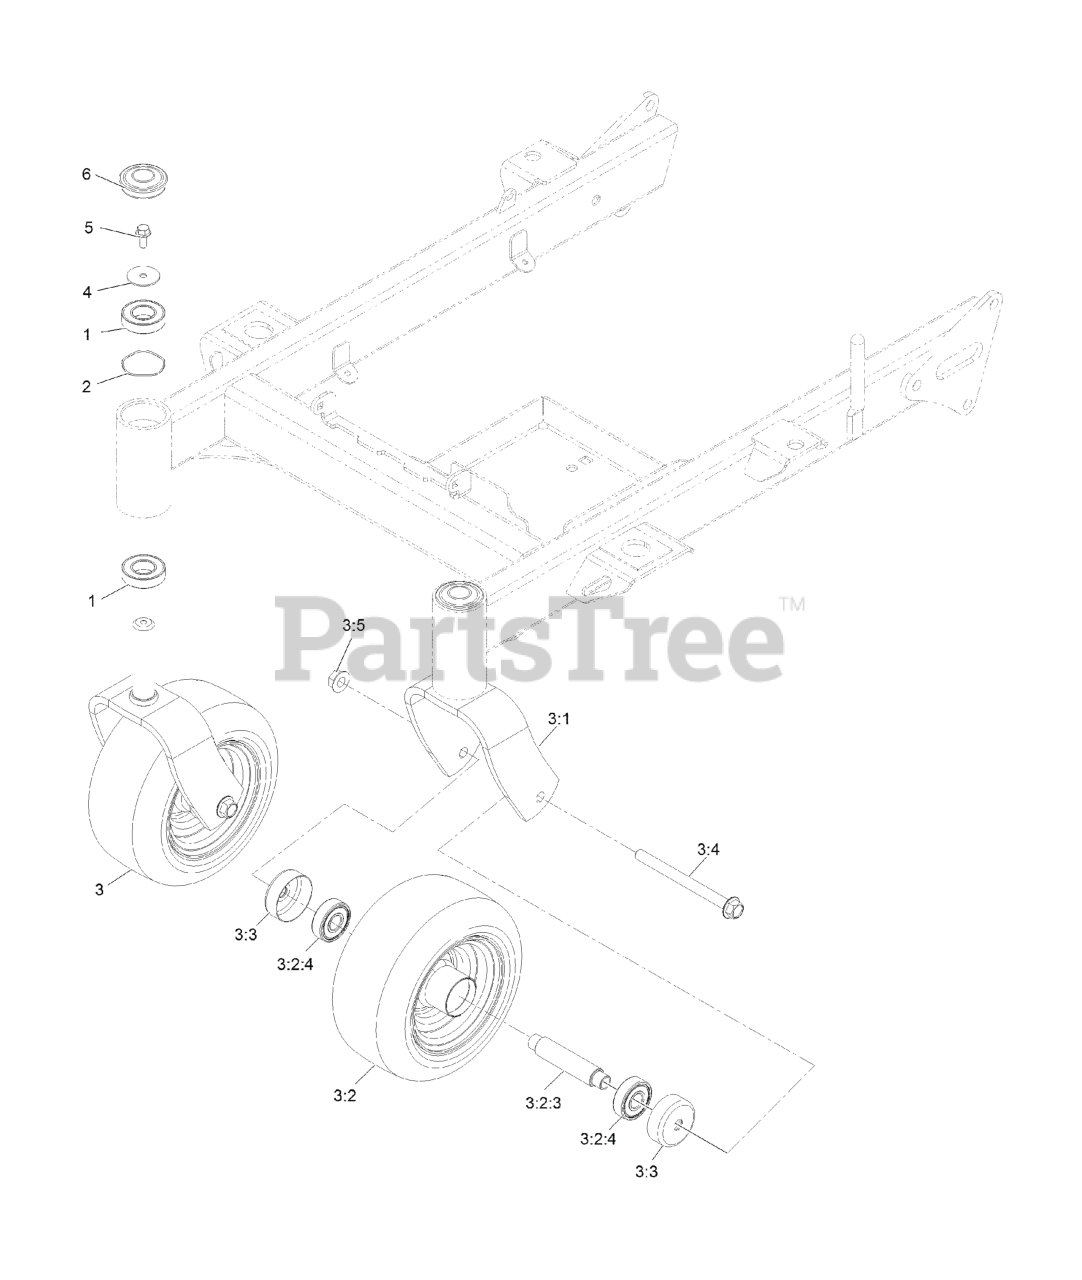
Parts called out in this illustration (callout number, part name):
1	BEARING-BALL
3	ASM-Caster Fork W/Tire
3:1	ASM-CASTER FORK
3:2	ASM-TIRE&WHL SP 9X4.50-5
3:2:3	AXLE-CASTER
3:2:4	BEARING
3:3	GUARD, SEAL
3:4	SCREW-HHF
4	WASHER-FLAT
5	SCREW-HHF
6	CAP-GREASE
